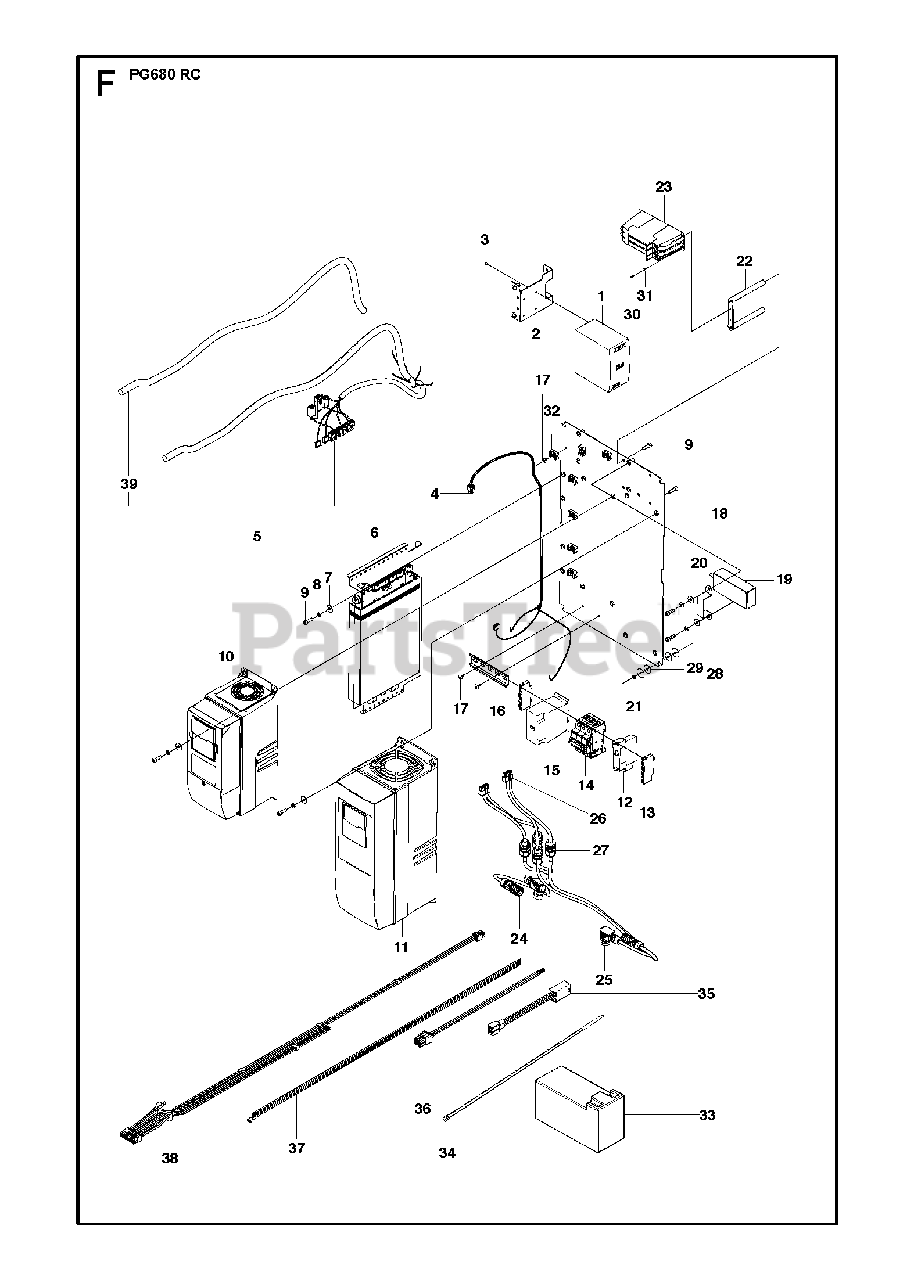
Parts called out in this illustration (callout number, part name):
21	HEXAGON LOCKING NUT
31	SPRING WASHER 4.1X7.1
35	HARNESSWIRING HARNESS - BATTERY
36	HARNESSWIRING HARNESS - CONTACTOR
37	HARNESSWIRING HARNESS - PSU PRIMARY
38	HARNESSWIRING HARNESS - POWER SECONDARY
